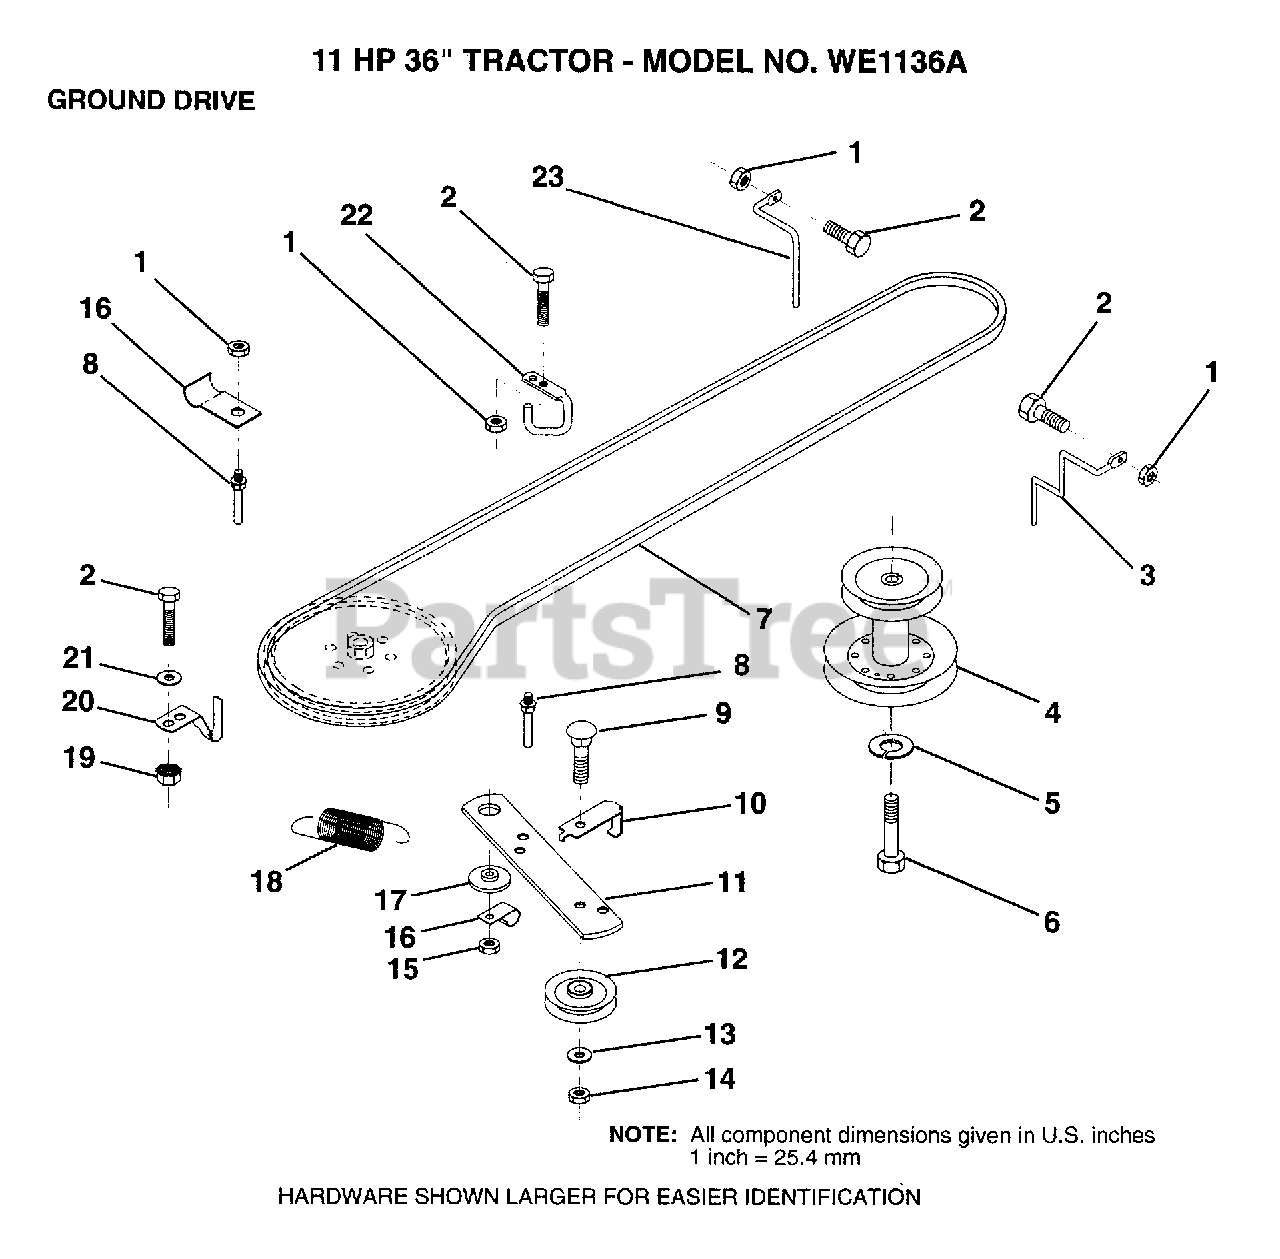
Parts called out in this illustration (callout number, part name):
2	BOLT
5	LOCKWASHER
6	HEX BOLT
7	BELT
8	"KEEPER,DRIVE BELT"
9	BOLT
10	"KEEP,IDLER DR BEL"
13	WASHER
14	LOCKNUT
16	"CLIP,INSULATOR"
17	SPACER RETAINER
20	"KEEPER,DR BELT "
21	WASHER
22	"KEEPER,FRA DR BEL"
